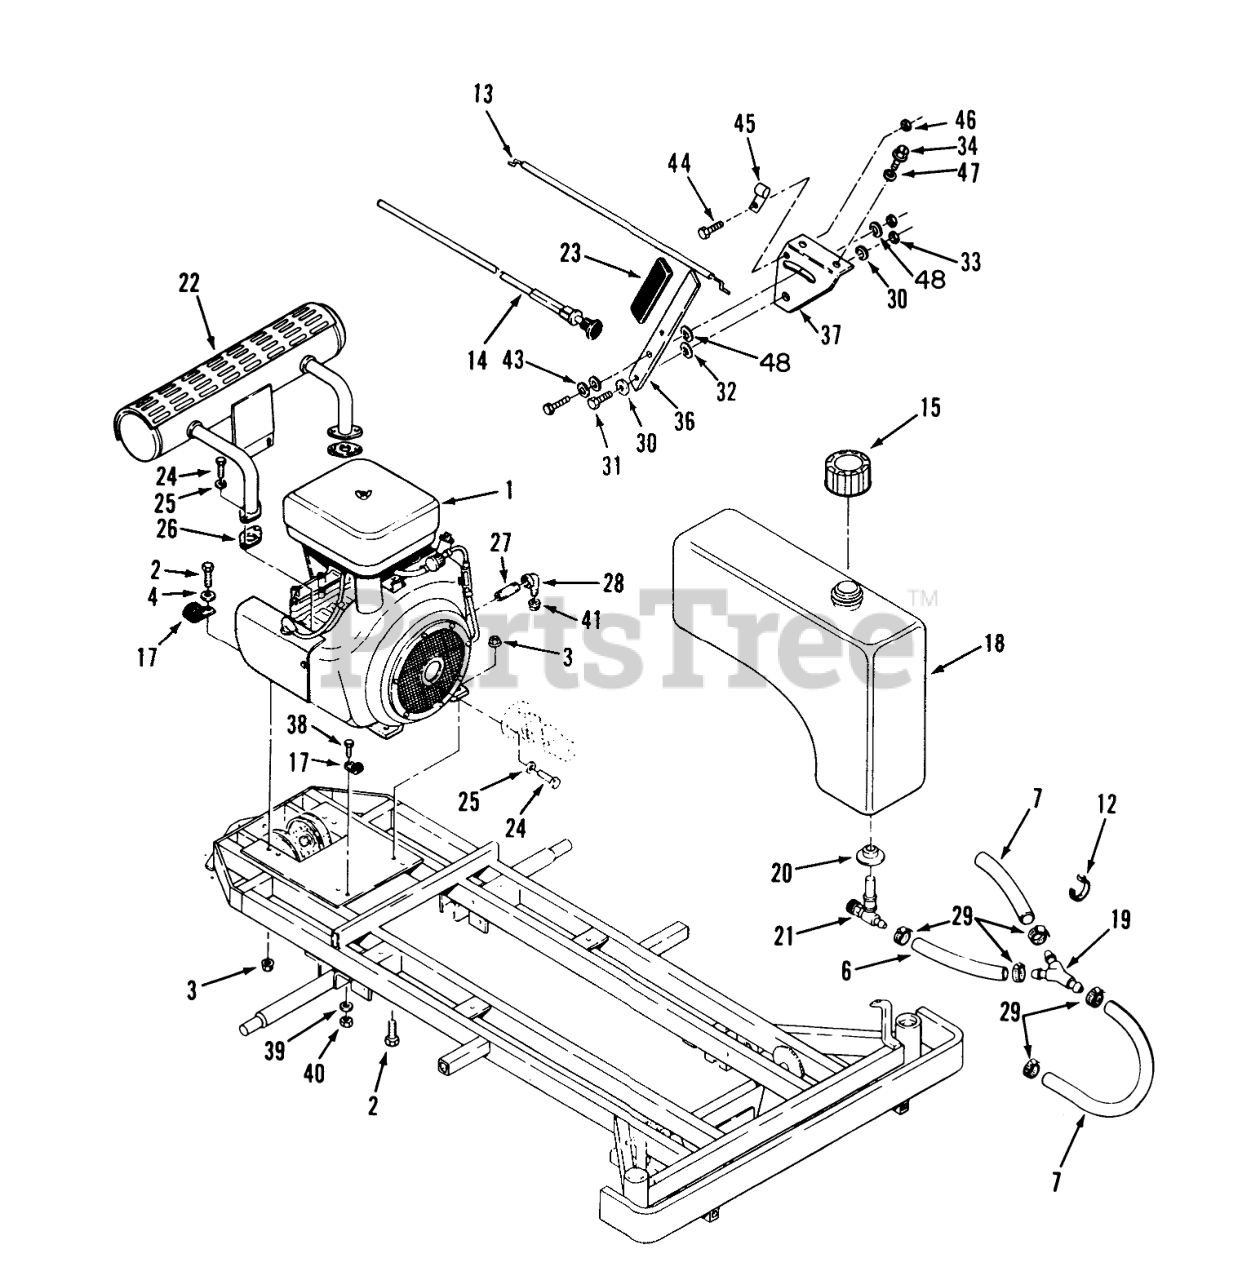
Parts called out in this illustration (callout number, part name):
1	Engine-24 HP Toro Power Plus P224 G I/10966 Spec. E Engine
2	SCREW-HH
3	NUT-LOCK, NI
4	WASHER-FLAT
6	HOSE-FUEL
7	HOSE-GAS
12	TIE-CABLE
13	CABLE-CHOKE CONTROL
14	CABLE-CHOKE
15	GAS CAP ASM
17	CLIP
18	Tank-Fuel (Incl. Items #20 & 21)
19	FITTING-FUEL 45-Y
20	BUSHING
21	VALVE-FUEL
22	MUFFLER
23	GRIP BRAKE20258-K
24	SCREW-HSH
25	WASHER-LOCK
26	GASKET-EXHAUST
27	Pipe
28	ELBOW-STREET, 90 DEG
29	CLAMP-HOSE
30	WASHER-FLAT
31	SCREW-HH
32	SPACER CLUTCH ARM
34	SCREW-HH
36	Handle
37	CABLE/BRKT ASM
38	SCREW-HH
39	WASHER-PLAIN
40	NUT-LOCK, NI
41	CAP-PIPE
43	WASHER-SPRING DISC
44	SCREW-HEX, MACHINE
45	CLIP BOWDEN WIRE
46	HEX NUT 10-32 E.S.
47	WASHER-LOCK
48	FRICTION WASHER
